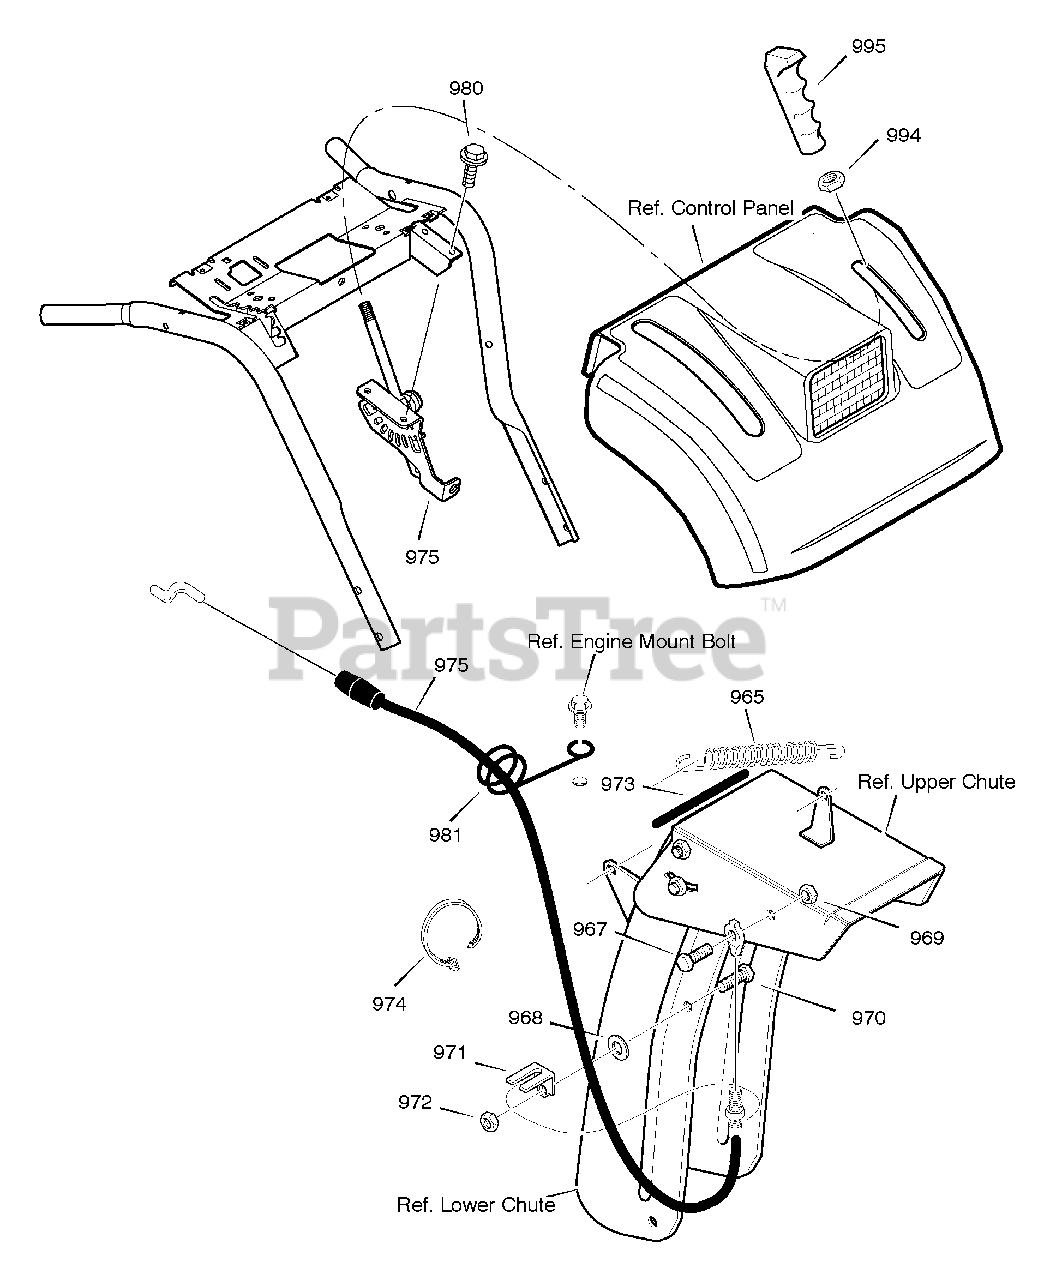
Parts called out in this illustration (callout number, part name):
965	TENSION SPRING
967	BOLT, SHOULDER
968	FLATWASHER
970	SCREW, 5/16-18 x 0.75
971	BRACKET, CABLE CHUTE
972	NUT, 5/16-18
973	TRIM STRIP, GREY
974	TIE, CABLE
975	CABLE, CHUTE DEFLECTOR
980	SCREW
981	WIRE FORM, CHUTE CABLE
994	NUT, 3/8-16
995	KNOB, SHIFT
